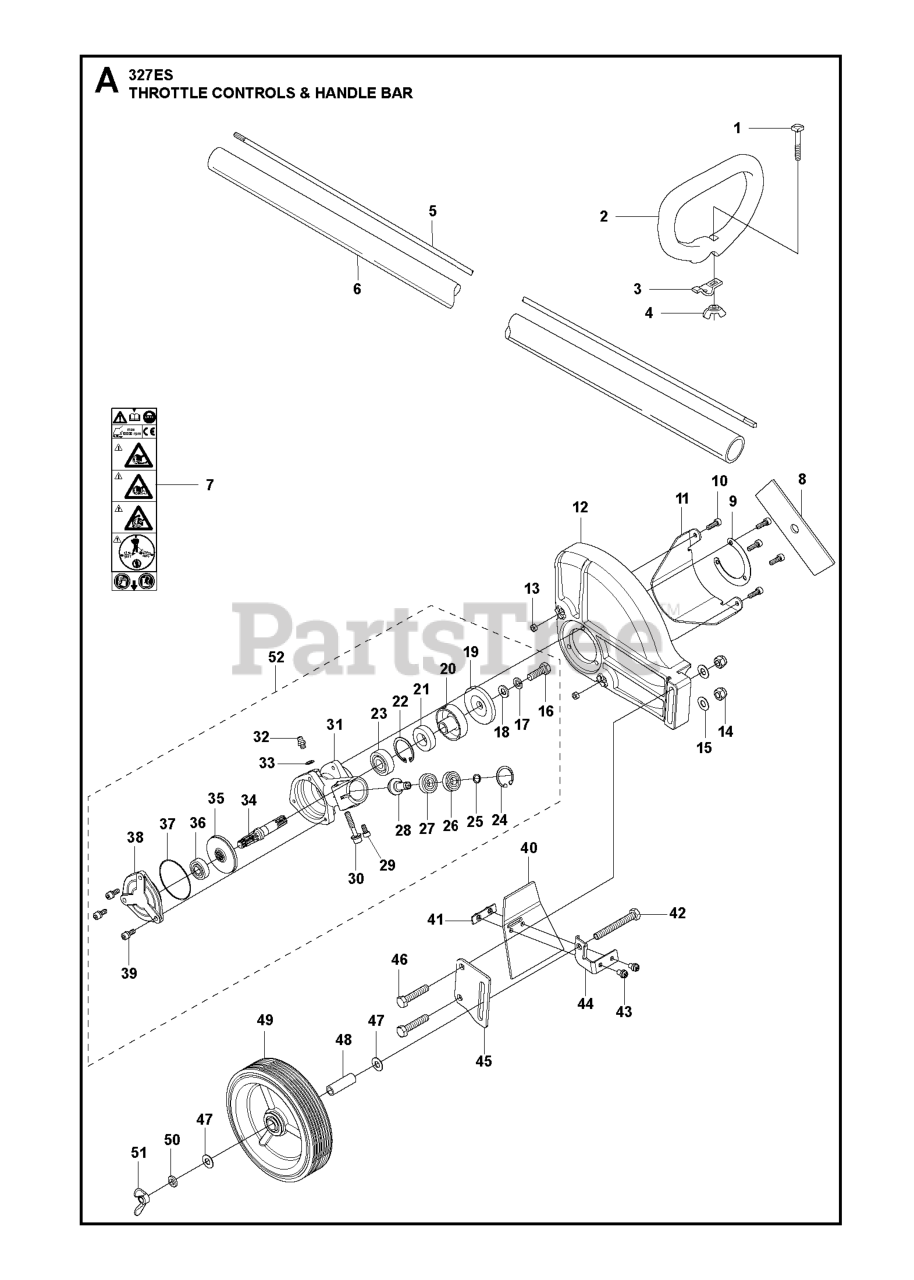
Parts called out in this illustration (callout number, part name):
2	HANDLE, LOOP
3	HOLDER
5	DRIVE SHAFT
6	DRIVE TUBE ASSEMBLY
7	LABEL WARNING
8	BLADE 7.52X2X.125
10	BOLT M5 X L16 ALLEN
11	PLATE, PROTECTOR
14	NUT
16	BOLT M8 X L25 L/H
19	HOLDER (B)
20	HOLDER (A)
24	RP_RING
29	BOLT M5 X L10 ALLEN BOLT
30	BOLT M6 X L35 ALLEN
39	BOLT M5 X L14 ALLEN
42	BOLT M8 X L65
43	BOLT M5 X L10
45	MAIN BRACKET
46	BOLT M8 X L40
51	RP_NUT
52	GEARCASE ASSY
